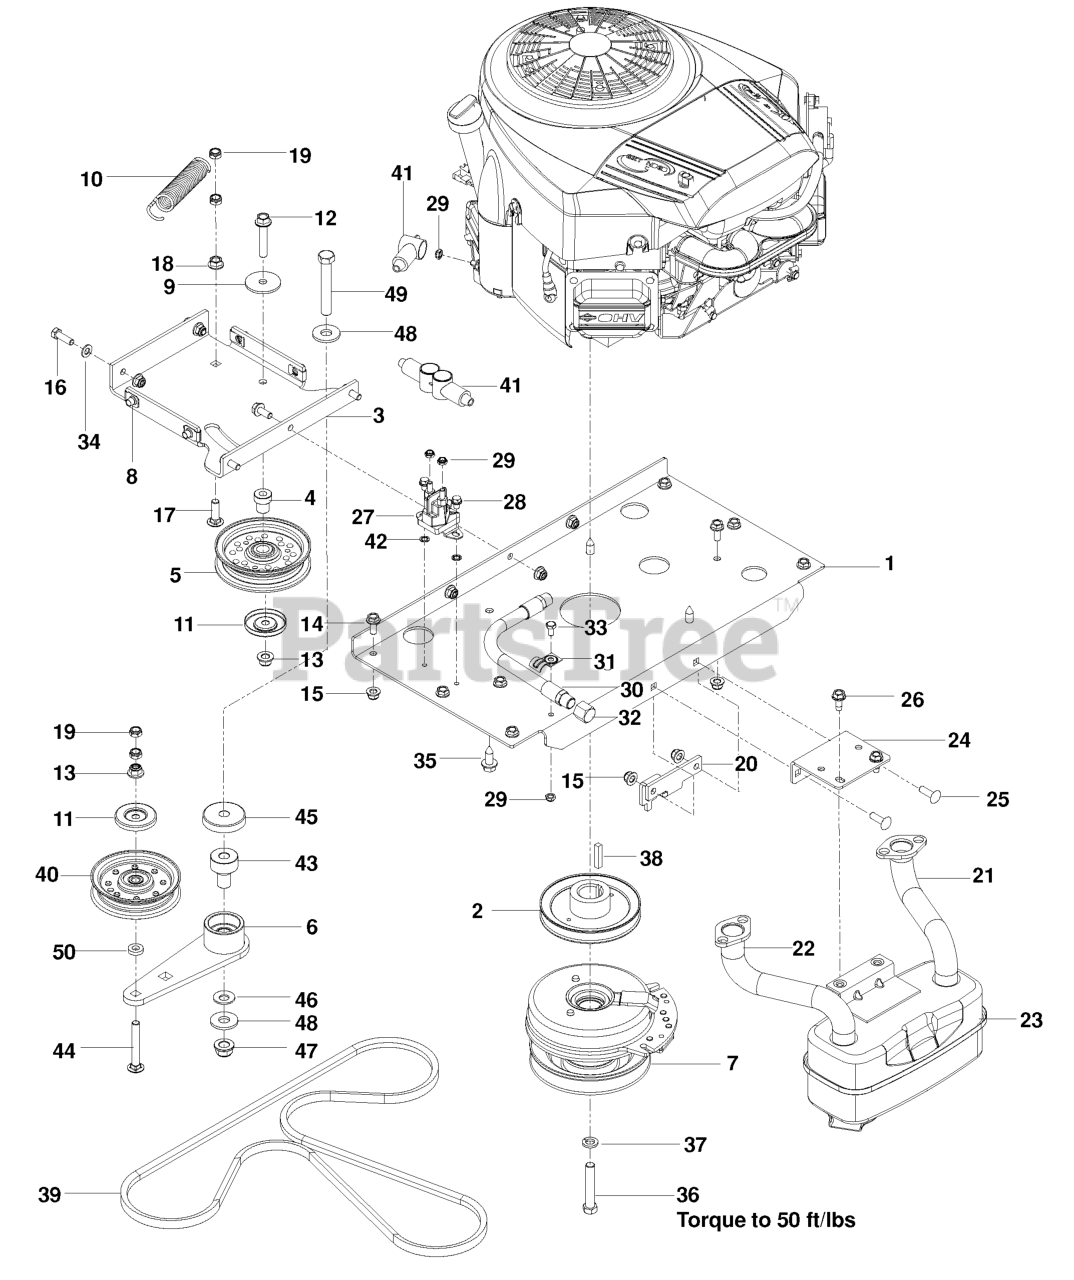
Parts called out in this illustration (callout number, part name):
1	PLATE, ENGINE W/DECALS
2	PULLEY, V, 1.125 BORE
3	PLATE, IDLER, BLK
4	PIVOT, IDLER
5	IDLER PULLEY
6	ARM, IDLER, STEEL, W/BGS
7	CLUTCH 200 FT LB
8	U-CLIP 5/16-18 NUT RETAINER
9	WASHER, 3/8 SPEC
10	SPRING, PUMP
11	DUST SHIELD
12	HHFS 3/8-16 X 2.0 GD 5
13	NUT 3/8-16 HEX FLG NYLOC ZD
14	HHFS 5/16-18 X 3/4
15	5/16-18 NYLOC FLANGE NUT
16	HCS 5/16C X 1
17	RHSNB 3/8-16 X 1-1/4
18	NUT 3/8C WHIZ
19	NUT HEX 3/8-16 NYLON, THIN
20	STOP, CLUTCH, BLACK
21	RP.EXHAUST.TUBE.LH.BS/TWIN
22	EXHAUST.TUBE.RH.BS/TWIN
23	MUFFLER ASM TWIN
24	BRKT, MUFFLER, BLK
25	RHSSNB 5/16C X 1.0
26	BOLT 5/16-18 X 3/4
28	HWST 1/4C X 3/8
29	JAM NUT 1/4C (2 2 PW01)
30	OIL DRAIN HOSE
33	HCS 1/4-20.
34	FLAT WASHER 5/16 SAE
35	HHFS 3/8-16 X 1.0 THD FORMING
36	BOLT 7/16F X 2 1/2
37	WASHER 7/16 LOCK
38	KEY, 1/4 SQ X 1 1/4
39	BELT, HYDRO, 3400
40	FLAT IDLER PULLEY
42	WASHER 1/4 INT TOOTH
43	PIVOT, BEARING
44	RHSNB 3/8-16 X 2.75
45	SHIELD, DUST
46	CONTACT BELLSPR 1/2
47	NUT, 1/2-13 HEX FLG NYLOC ZD
48	WASH USS FLAT 1/2
49	HCS 1/2C X 3 1/4
50	WASHER 3/8 X 3/4 X .187 TK
